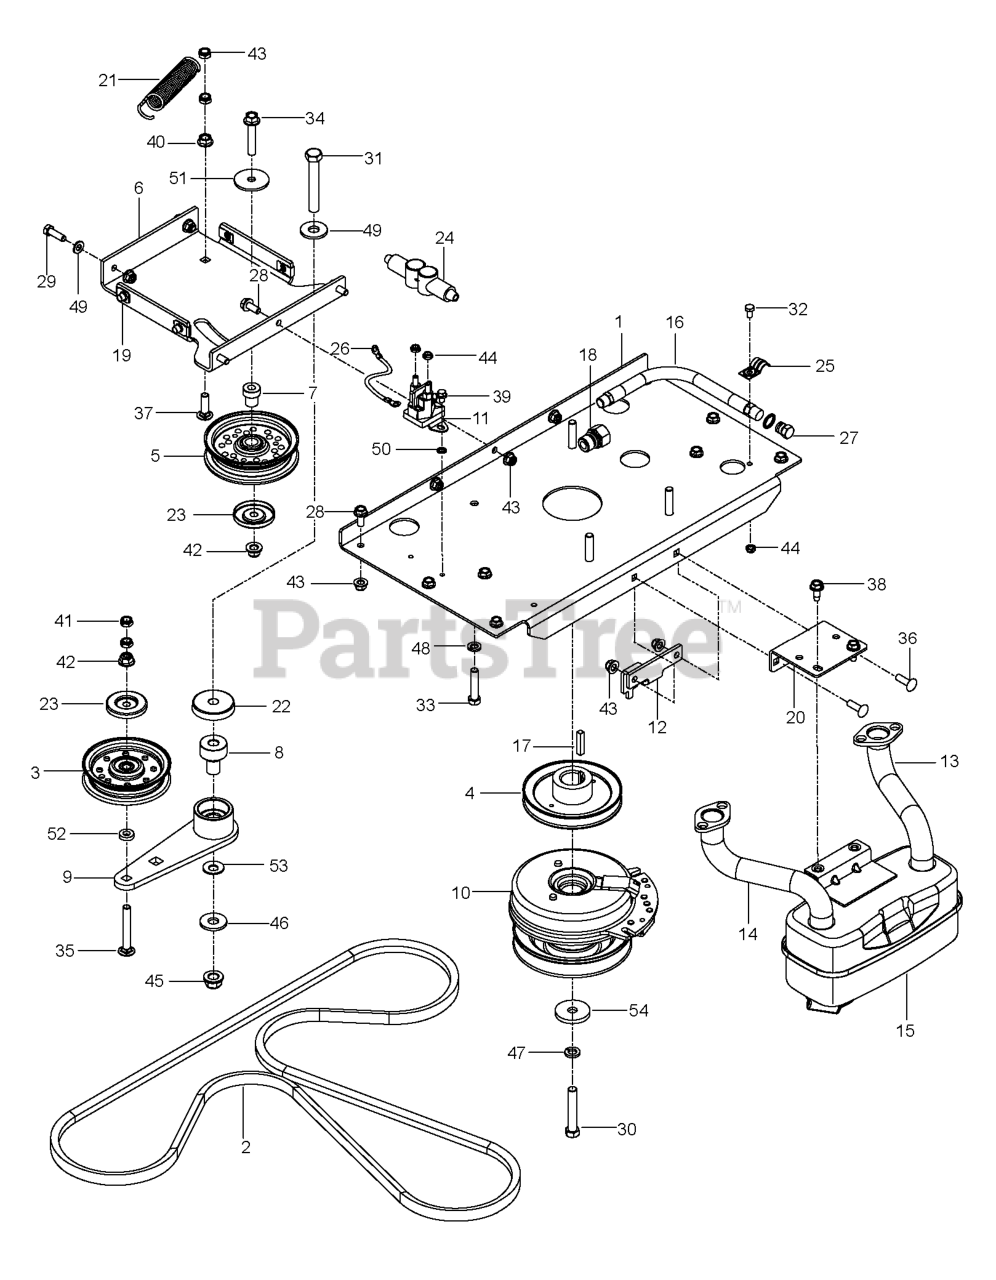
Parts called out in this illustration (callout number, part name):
1	PLATE, ENGINE W/DECALS
2	BELT, HYDRO, 3400
3	PULLEY.IDLER.FLAT.46.PR.DR.
4	PULLEY, V, 1.125 BORE
5	IDLER PULLEY
6	PLATE, IDLER, BLK
7	PIVOT, IDLER
8	PIVOT, BEARING
9	ARM, IDLER, STEEL, W/BGS
10	CLUTCH 200 FT LB
12	STOP, CLUTCH, BLACK
13	TUBE.EXHAUST.LH.FR961/FR730
14	TUBE.EXHAUST.RH.FR961/FR730
15	MUFFLER ASM TWIN
16	HOSE.ASSEMBLY.OIL.DRAIN
17	KEY, 1/4 SQ X 1 1/4
18	ADAPTER, OIL DRAIN
19	U-CLIP 5/16-18 NUT RETAINER
20	BRKT, MUFFLER, BLK
21	SPRING, PUMP
22	SHIELD, DUST
23	DUST SHIELD
26	CABLE POSITIVE
27	PLUG OIL DRAIN
28	HHFS 5/16-18 X 3/4
29	HCS 5/16C X 1
30	CLUTCH BOLT7/16-20X2.5 GR596HR
31	HCS 1/2C X 3 1/4
32	HCS 1/4-20.
33	BOLT, HCS 3/8-16X1-3/4
34	HHFS 3/8-16 X 2.0 GD 5
35	RHSNB 3/8-16 X 2.75
36	RHSSNB 5/16C X 1.0
37	RHSNB 3/8-16 X 1-1/4
38	SCREW.THDROL.5/16-18X3/4.TTY
39	HWST 1/4C X 3/8
40	NUT 3/8C WHIZ
41	NUT HEX 3/8-16 NYLON, THIN
42	NUT 3/8-16 HEX FLG NYLOC ZD
43	5/16-18 NYLOC FLANGE NUT
44	JAM NUT 1/4C (2 2 PW01)
45	NUT, 1/2-13 HEX FLG NYLOC ZD
46	WASH USS FLAT 1/2
47	WASHER 7/16 LOCK
48	SLW 3/8 STD
49	FLAT WASHER 5/16 SAE
50	WASHER 1/4 INT TOOTH
51	WASHER, 3/8 SPEC
52	WASHER 3/8 X 3/4 X .187 TK
53	CONTACT BELLSPR 1/2
54	SPINDLE WASHER
